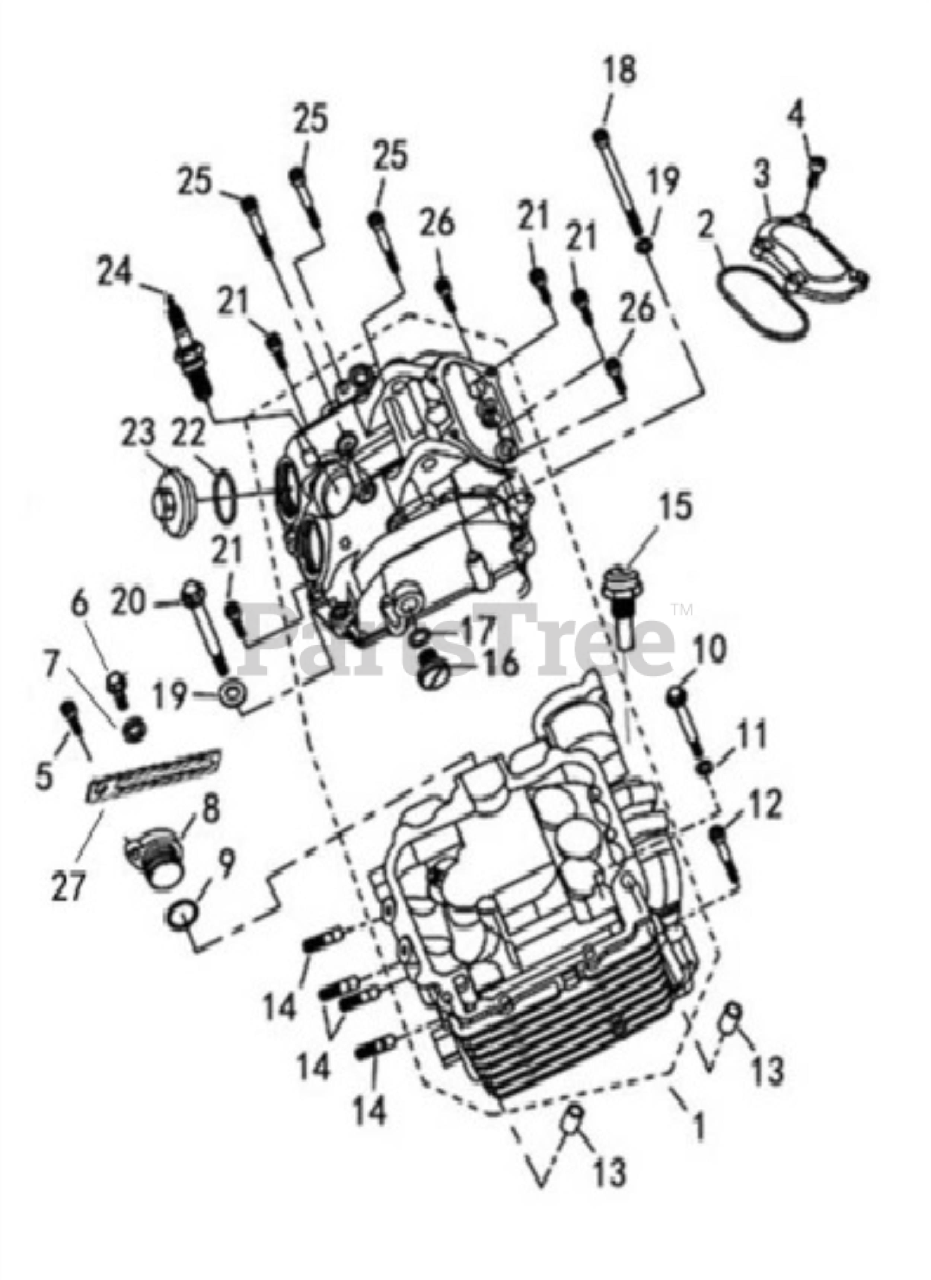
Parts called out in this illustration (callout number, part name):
1	Cylinder Head assy
2	O-Ring 71.5x3
3	Cover,Intake Valve
4	Hex head cap screw M6x20
5	Hex head cap screw M6x20
6	Hex flange bolts M6x12
7	Aluminum Washer 6x12x1.5
8	Camshaft End Cover
9	O-RING 18 x 2.4
10	Cylinder bolts M9x109
11	Washer 10x19x2
12	Hex head cap screw M6x50
13	Pin,Dowel 10x16
14	Stud M8x45(SUS)
15	Water Temperature Sensor
16	Small Peep Hole Cover
17	O-Ring 13.4x2.35
18	Hex head cap screw M6x130
19	Aluminum Washer 6x12x2
20	Hex head cap screw M6x115
21	Hex head cap screw M6x25
22	O-Ring 32.7x3.1
23	Cover,Exhaust Valve
24	Spark Plug NGK DCPR7E
25	Hex head cap screw M6x55
26	Hex head cap screw M6x40
